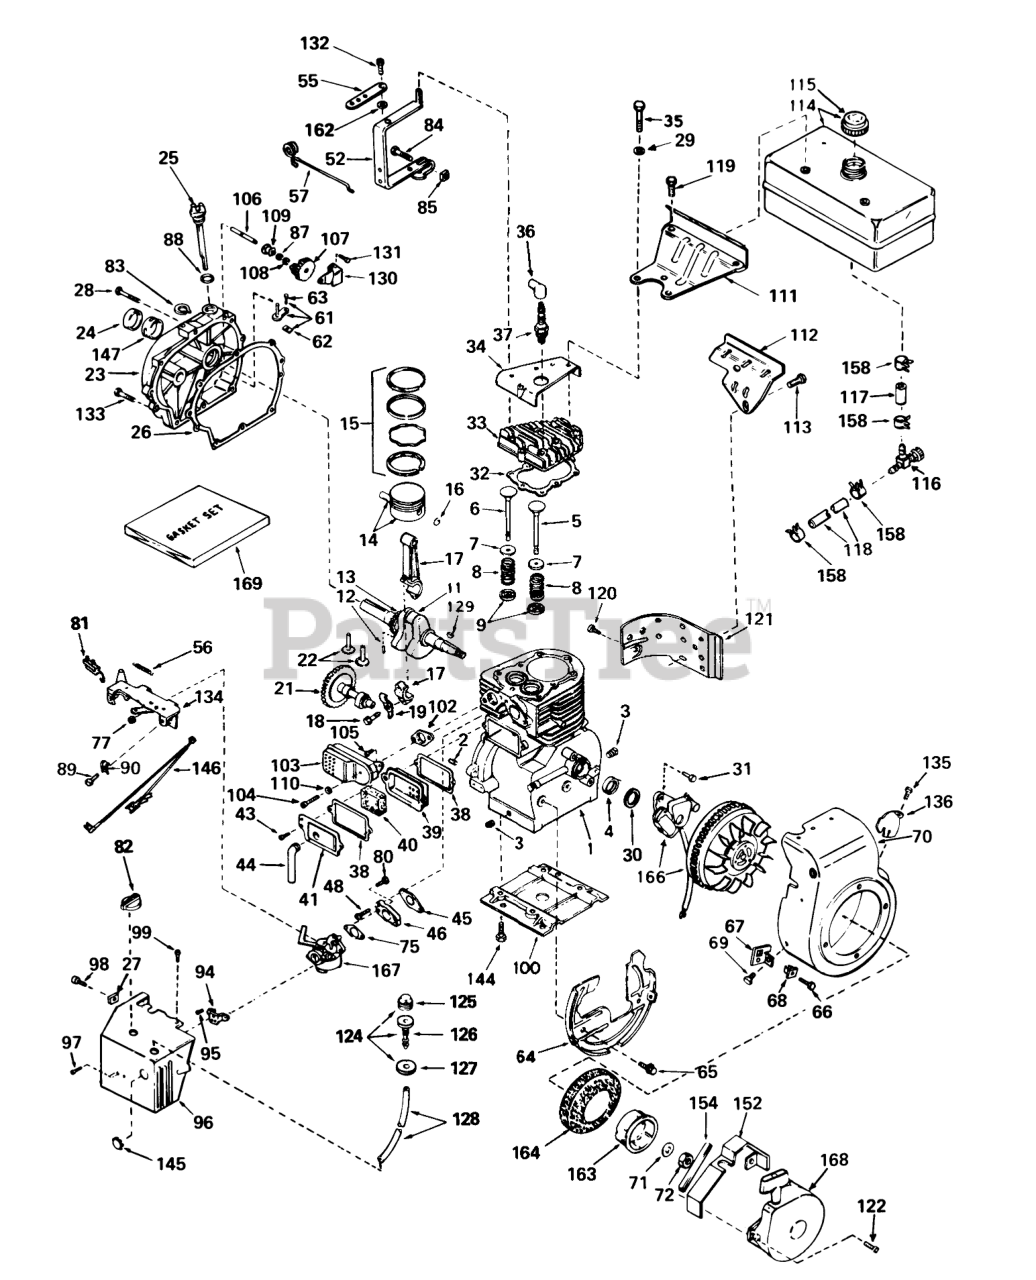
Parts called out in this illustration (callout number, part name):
1	Cylinder Assembly (Incl. Ref. #2, 3 & 4)
2	Pin-Dowel
3	Plug-Drain, Oil (SQH 1/4-18)
4	Oil Seal
5	Valve, Intake (Std.) (Incl. Ref. #9)
5	Valve, lntake (1/32" Oversize) (Incl. Ref. #9)
6	Valve, Exhaust (Std.) (Incl. Ref. #9)
6	Valve, Exhaust (1/32" Oversize) (Incl. Ref. #9)
7	Cap-Spring, Valve
8	Spring-Valve
9	Keeper-Spring, Valve
11	Crankshaft Assy., (Incl. Ref. #12 & 13)
12	Pin, Groove
13	Gear-Crankshaft
14	Piston & Pin Assy. (Incl. Ref. #16) (Std.)
14	Piston, Pin & Ring Assy. (Incl. Ref. #15 & 16) (Std.)
14	Piston & Pin Assy. (Incl. Ref. #16) (.010 Oversize)
14	Piston, Pin & Ring Assy. (Incl. Ref. #15 & 16) (.010 Oversize)
14	Piston & Pin Assy. (Incl. Ref. #16) (.020 Oversize)
14	Piston, Pin & Ring Assy. (Incl. Ref. #15 & 16) (.020 Oversize)
15	"O"Ring
15	Ring Set (.010" OS)
15	Ring Set (.020" OS)
16	Ring-Retaining, Piston Pin
17	Rod Assy., Connecting (Incl. Ref. #18 & 19)
18	Bolt, Connecting Rod
19	Dipper-Oil
21	55012A GIL SNWTHWR
22	Lifter-Valve
23	Cover, Cylinder (Incl. Ref. #24, 106 & 147)
24	Oil Seal
25	Dipstick, Oil (Incl. Ref. #88)
26	Gasket-Cover, Cylinder
27	Nut-U Type
28	Screw (1/4-20 x 1-1/4)
29	Washer-Flat
30	Gasket Stator
32	Gasket-Cylinder Head
33	CYLINDER HEAD
34	Cover-Head, Cylinder
35	Screw (5/16-18 X 2-1/2)
36	Cover-Spark Plug
37	Plug, Spark (J17LM or equiv.)
37	Plug, Spark (Champion RCJ-8)
38	Gasket-Breather
39	Body-Breather
40	Element-Breather
41	Cover-Valve
44	Tube-Breather
45	Gasket-Intake
46	Flange, Carburetor (Incl. Ref. #77 & 80)
52	Lever, Governor
55	Bracket Governor adjusting
56	Spring, Extension
57	Link, Governor to Throttle
61	Rod Assy., Governor (Incl. Ref. #62 & 73)
62	Yoke-Governor
63	Screw (6-40x5/16)
64	Baffle Blower Housing
65	Screw (1/4-20x19/32)
66	Screw
67	Bracket
68	Grommet
69	Screw, Hex Hd.
70	Housing, Blower (Incl. Ref. #135 & 136)
71	Washer
75	Gasket-Carburetor
77	Nut and Lock Washer (1/4-28)
80	Screw
81	Terminal
82	Knob-Control
83	Ring-Retaining
85	Nut-Lock
87	Washer-Flat
88	Gasket
89	Screw (10-32 x 3/8)
90	Conduit
94	Bracket-Choke
95	Screw (10-32 x 1/2)
96	Cover, Carburetor
97	Screw (8-32 X 5/16)
98	Screw (8-32 x 3/8)
99	Screw (10-32x1/2)
100	Base Engine
102	Gasket Exhaust
103	Muffler
104	Screw (5/16-18 X 2)
106	Shaft-Governor
107	Gear Assy., Covernor (Incl. Ref. #87)
108	Ring-Retaining
109	Spool-Governor
111	Bracket-Fuel Tank
112	Bracket-Fuel Tank
113	Screw (1/4-20x19/32)
114	Tank Assy., Fuel (Incl. Ref. #115)
115	Cap, Fuel
116	Valve-Shut Off
117	Line-Fuel (8.62)
118	Line-Fuel
119	Screw (1/4-15x7/8)
121	Emnsion, Blower Housing
124	Primer Assy. (Incl. Ref. #125, 126 & 127)
125	33164A GILO"HITCH A
126	Body Primer
127	Retainer, Primer Bulb
128	Line, Primer
129	Key-Flywheel
130	Bracket, Governor
131	Screw (10-32 x 35/64)
132	Screw
134	Control Assy., Remote Speed (Incl. Ref. #56 & 81)
135	Screw, Pan Hd.
146	Wire, Ground
147	Bushing-Crankshaft
152	Guard-Starter
154	Seal, Snowguard
158	Clamp-Line, Fuel
162	Washer-Lock
163	Cup-Starter
164	Screen, Air
167	Carburetor (Incl. Ref. #75)
168	Starter Assy., Rewind
169	Gasket Set
